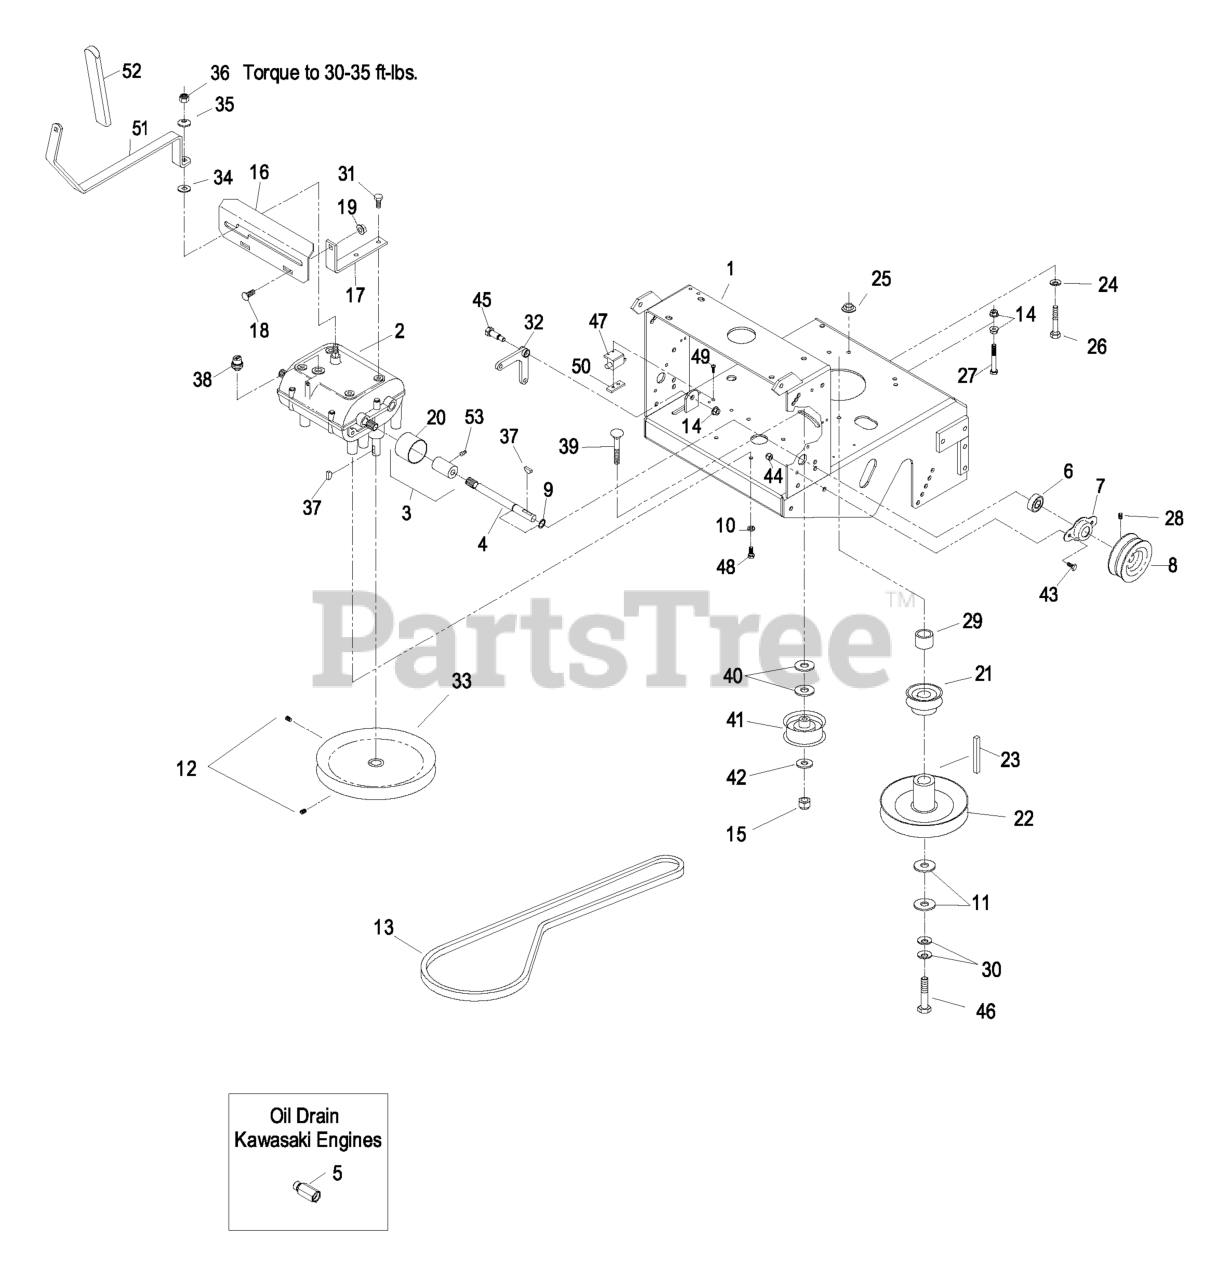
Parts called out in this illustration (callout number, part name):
3	ASM,COUPLER/ZERK
4	SHAFT-TRANSMISSION
5	ADAPTER
6	BEARING-SHAFT
7	FLANGE-OUTPUT
8	SHEAVE-TRANSMISSION
9	RING-RETAINING
10	WASHER-LOCK
12	SCREW-HSH
13	BELT,TRANS DRIVE
14	NUT-HHF, WHIZ
15	NUT-LOCK, NI
16	PLATE,SHIFTER W/DECAL
17	BRACKET-PLATE, SHIFT
18	BOLT-CARR
20	GUARD-COUPLER
21	SHEAVE-TRANSMISSION
23	KEY-SQUARE
24	WASHER-SPRING
26	SCREW-HH
27	SCREW-HH
28	SCREW-SET
29	SPACER-CLUTCH
30	WASHER-SPRING
31	SCREW-HWH, THREAD CUT
32	BELLCRANK
33	SHEAVE-TRANSMISSION
35	WASHER-BELLEVILLE
36	NUT-LOCK
37	KEY-WOODRUFF
38	SWITCH-START, NEUTRAL
39	SCREW-HH
40	WASHER-FLAT
42	WASHER-FLAT
43	SCREW-HH
44	NUT-LOCK, NI
45	BOLT-SHOULDER
46	SCREW-HH
47	SWITCH-OPEN, NORMALLY
48	SCREW-HH
49	SCREW-PPH
50	PLATE-TAPPED
51	ASM,SHIFT LEVER
52	GRIP,FOAM
53	FITTING-GREASE
